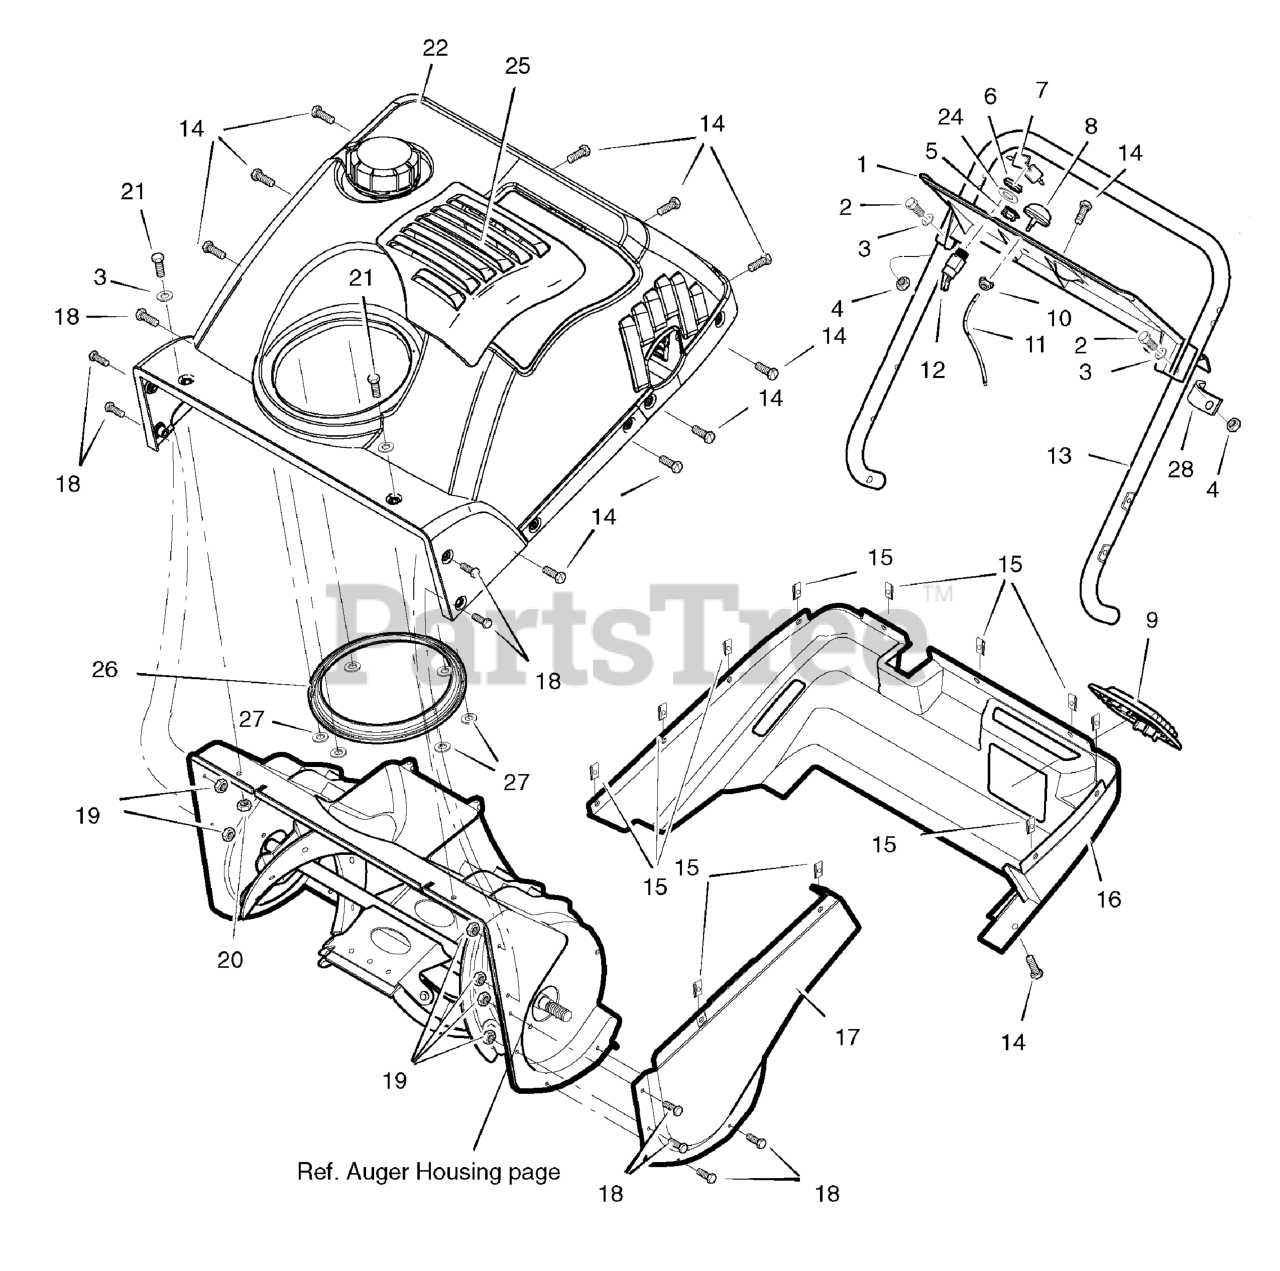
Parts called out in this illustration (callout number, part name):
1	PANEL, Control
2	SCREW, 1/4 - 20 x 1-1/4
3	WASHER
4	NUT, 1/4 - 20
5	BUSHING, Chute Crank
6	NUT, 5/8 - 32
7	KEYS & RING, Starter
8	BULB, Fuel Primer
9	PANEL, Access
10	NUT, Keps 1/4 - 20
11	HOSE, Primer, 9.5"
12	SWITCH, Ignition
13	HANDLE, Lower
14	SCREW, 1/4 - 14 x 3/4
15	NUT, 1/4 - 10
16	COVER, Bottom
17	COVER, Belt
18	SCREW, 10 - 24 x 1/2
19	NUT, Hex Center Lock, 10 - 24
20	LOCKNUT, Hex 1/4 - 20
21	SCREW, 1/4 - 20 x 5/8
22	COVER, Top
25	COVER, Auger Top 22"
26	Gasket, Chute Ring
27	NUT, Push Pal
28	CLIP, Cable
